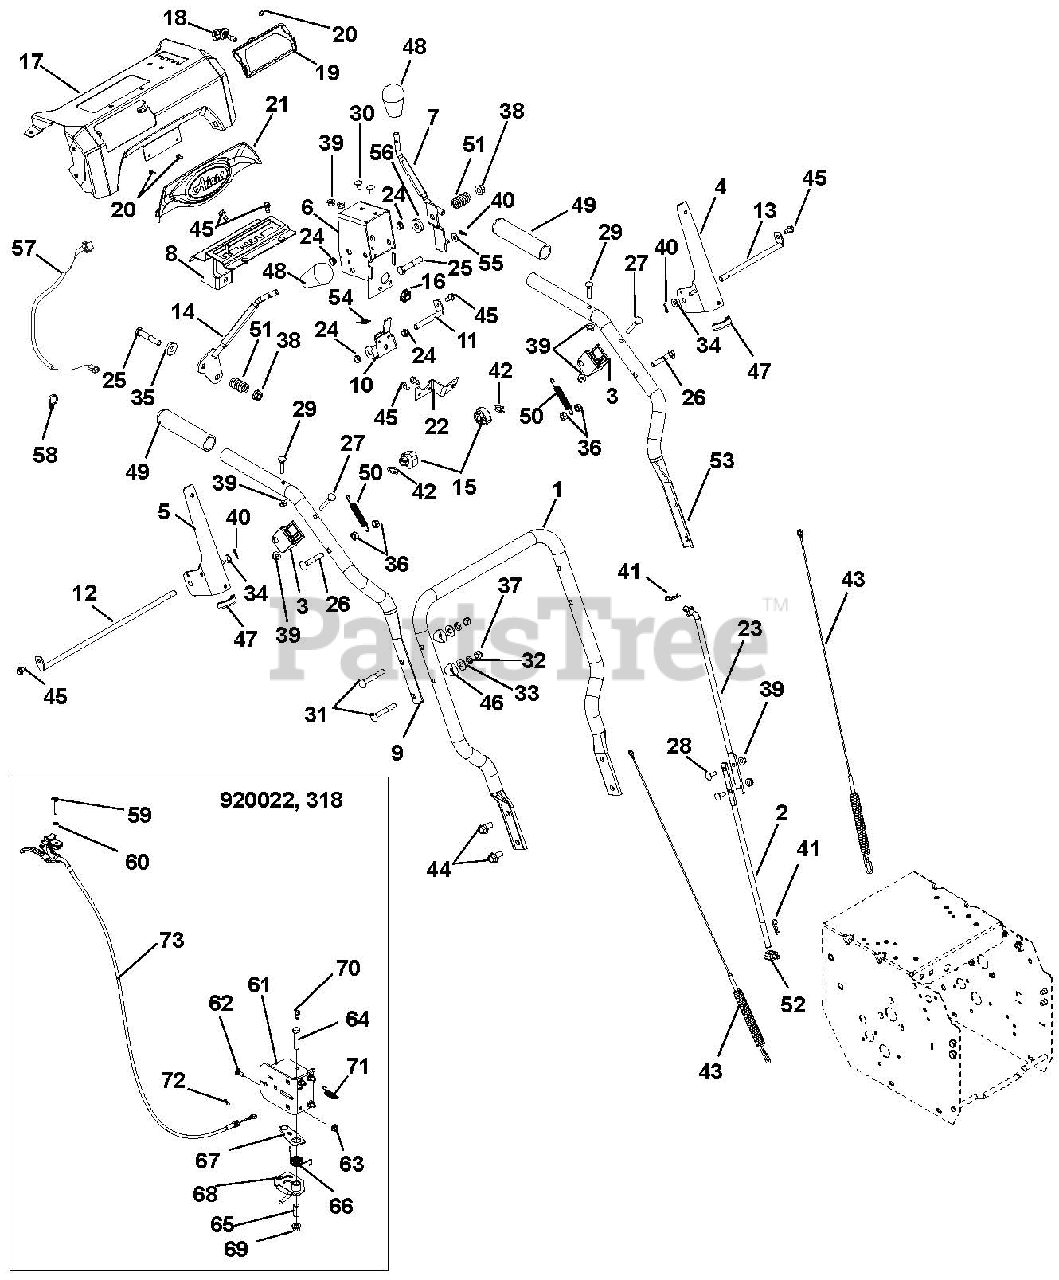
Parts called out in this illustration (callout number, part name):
1	HANDLEBAR, LOWER (COMPACT)
2	ROD, SHIFT - LOWER
3	BLOCK, CLUTCH PADDLE
4	LEVER, CLUTCH-LH
5	LEVER, CLUTCH-RH
6	WELDMENT, BRACKET INTERLOCK
7	WELDMENT, CONTROL LEVER (DEFL)
8	WELDMENT, DETENT PLATE-COMPACT
9	HANDLEBAR, UPPER - RH
10	BRACKET, INTERLOCK ARM
11	ROD, PIVOT - INTERLOCK
12	ROD, PADDLE MOUNT - LONG
13	ROD, PADDLE MOUNT - SHORT
14	LEVER, CONTROL-SHIFT(WELDMENT)
15	CAM, INTERLOCK
16	CRANK BUSHING, NYLON CHUTE BK
17	CONTROL PANEL W/DECAL, ARIENS
17	CTRL PANEL W/DECAL, ARIENS REM
17	CONTROL PANEL W/DECAL, CMPT TK
18	BULB, LIGHT-HALOGEN 20W
19	HEADLIGHT ASSY, HALOGEN 20W
20	SCR-TAP #10X.50 BOSS INDHXHD
21	DASH BEZEL, ARIENS LOGO - COMP
22	ANCHOR, DEFLECTOR CABLE
23	ROD, SHIFT - UPPER
24	BUSHING, POLYLINER-.38 SNAPIN
25	@BLT-HEX .38-16X2.00 GR5 YWZC
26	BLT-RDHDXLSQNK .31-18X2.0 G5YZ
27	BLT-RDHDXLSQNK .25-20X2.0 G5YZ
28	@BLT-RDHDSQNK .25-20X.75 G5YZ
29	BLT-RDHDXLSQNK.25-20X1.25 G5ZC
30	@BLT-RDHDSQNK .25-20X.50 G5YZ
31	@BLT-RDHDSQNK .31-18X2.25 G5YZ
32	WSHR-LK .312X.097 HVY YWZC
33	@WSHR-FL-STL.38X.875X.083 YWZC
34	@WSHR-FL-STL.281X.62X.065 YWZC
35	WSHR-FL-STL .406X1.00X.188 YWZ
36	@NUT-LK-CTR .31-18 YWZC
37	@NUT-LK-NYL .312-18 YWZC
38	@NUT-LK-TOP-FLG .38-16 YWZC
39	@NUT-LK-CTR-FLG .25-20 YWZC
40	PIN-HAIR INT .06X.18X.77
41	PIN-HAIR INT .08X.18X1.18 YWZC
42	PIN, SPRING CLIP
43	CABLE, AUGER & UPPER TRACTION
44	BLT-SERHFWH .38-16X.75 YWZC
45	SCR-TAP .25-20X.50 HWH TR YWZ
46	SPACER, HANDLEBAR
47	EDGING, CLUTCH PADDLE - 2.00"
48	KNOB,SOFT TEARDROP,PUSH-ON GRY
49	HANDLE GRIP
50	SPRING, EXTENSION
51	SG-COMP .125X.781X1.250
52	PIVOT,SHIFT ROD .375-16(TRUNN)
53	HANDLEBAR, UPPER - LH
54	SPRING-EXT .047X.438X1.45
55	BSHG-SLV .265X.500X.219
56	WSHR-FL-STL .380X1.50X.062 YWZ
57	HARNESS, LIGHT - COMPACT
58	CABLE TIE LG 5-1/2
59	SCR-MCH .25-20X1.50 OVAL HD
60	WSHR-LK-INT .250 TH TYA
61	BRACKET, HEIGHT ADJUSTER
62	@BLT-RDHDSQNK .25-20X.75 G5YZ
63	@NUT-LK-CTR-FLG .25-20 YWZC
64	@BLT-HEX .38-16X1.75 GR5 YWZC
65	BSHG-SLV .385X.500X1.045
66	SG-TORS .067X.88
67	ARM, OVERTRAVEL
68	LOCK, HEIGHT ADJUSTER
69	NUT-LK-CTR-FLG .38-16 YWZC
70	SCR-TAP .25-20X.50 HWH TR YWZ
71	SPRING-EXT .047 X .438 X 1.85
72	PIN-HAIR INT .06X.18X.77
73	CABLE, TRACK REMOTE
